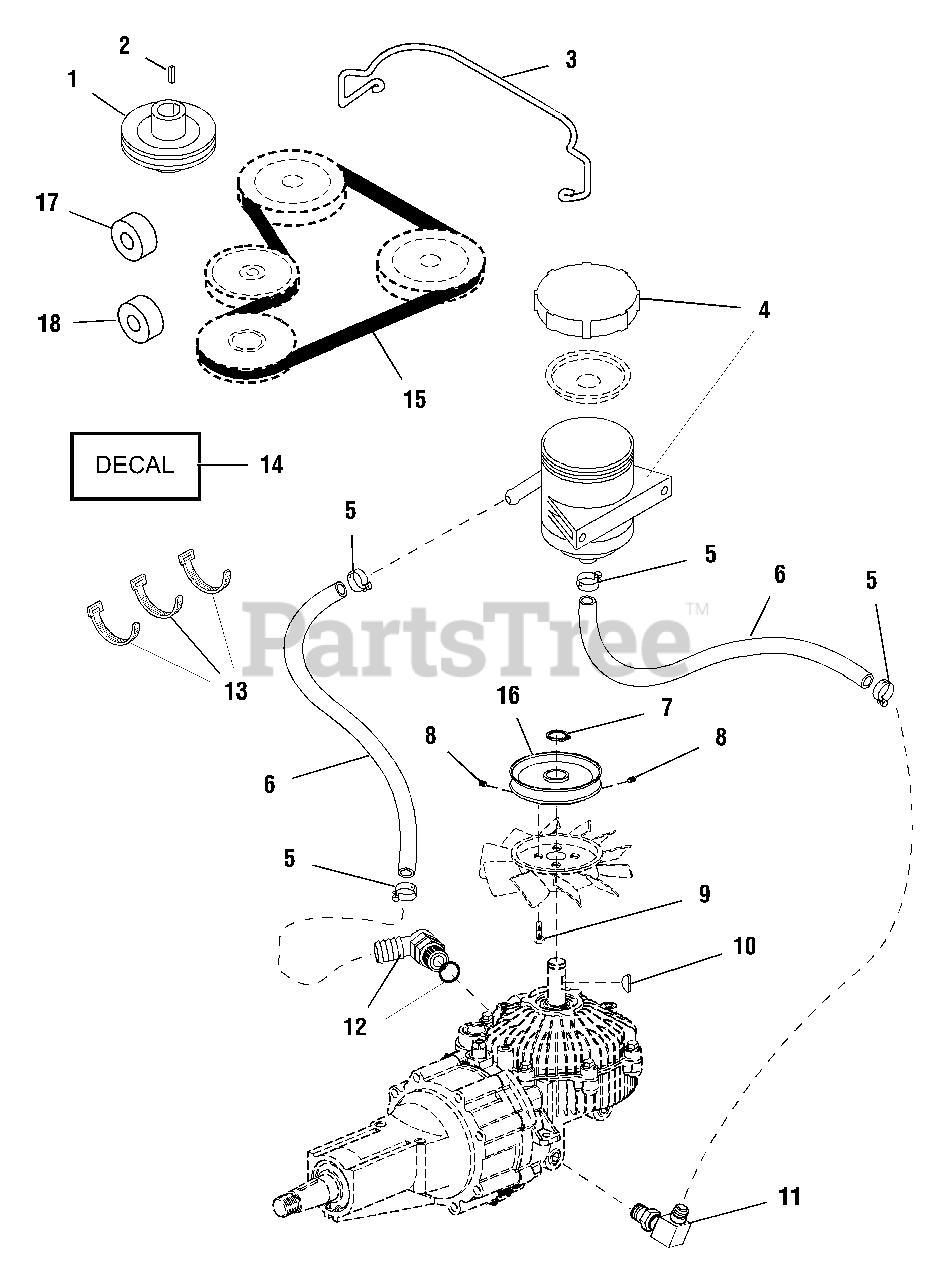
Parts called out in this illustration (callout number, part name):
1	PULLEY ASSY, PTO
2	KEY, Hi-Pro
5	CLAMP, Spring
6	HOSE, RH, 21"
6	HOSE, LH, 26"
7	RETAINING RING, 1/4-28 x 1/4
8	SET SCREW, Hex, 1/4-20 x 5/8
9	SCREW, Taptite,
10	KEY, Drive Pulley
11	FITTING, 90°, Steel
12	FITTING, 90°, Plastic
14	DECAL, Oil Res.
15	V-BELT,
16	PULLEY ASSY, Trans.
17	SPACER, Carrier, Rear, 1 x 1/2 x 11/32
18	SPACER, Carrier, Front, 1 x 1/2 x 17/64
